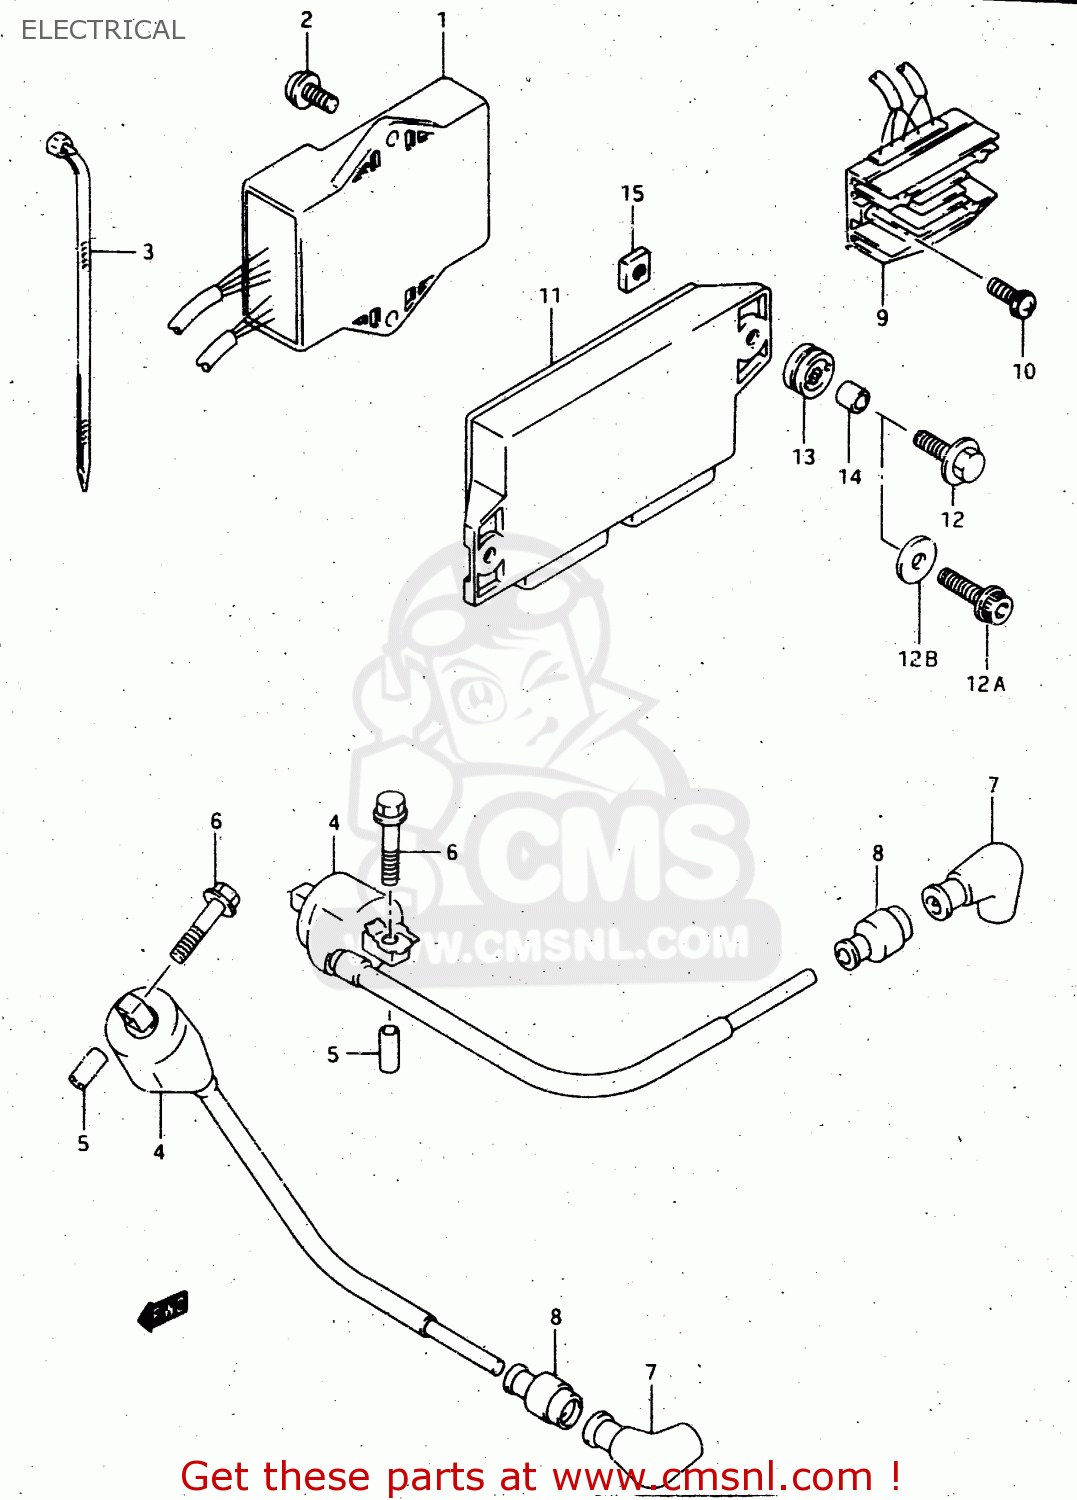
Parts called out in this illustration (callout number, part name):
1	CDI UNIT
2	SCREW
3	CLAMP(L:165)
4	COIL ASSY,IGNITION NO.1
5	SPACER
6	BOLT
7	CAP,SPARK PLUG
8	SEAL,HIGH TENSION CORD
9	RECTIFIER ASSY
10	SCREW
11	CONTROL UNIT
12	BOLT 6X25
12A	BOLT
12B	WASHER (6.5X20X1.2)
13	CUSHION
14	SPACER
15	NUT
